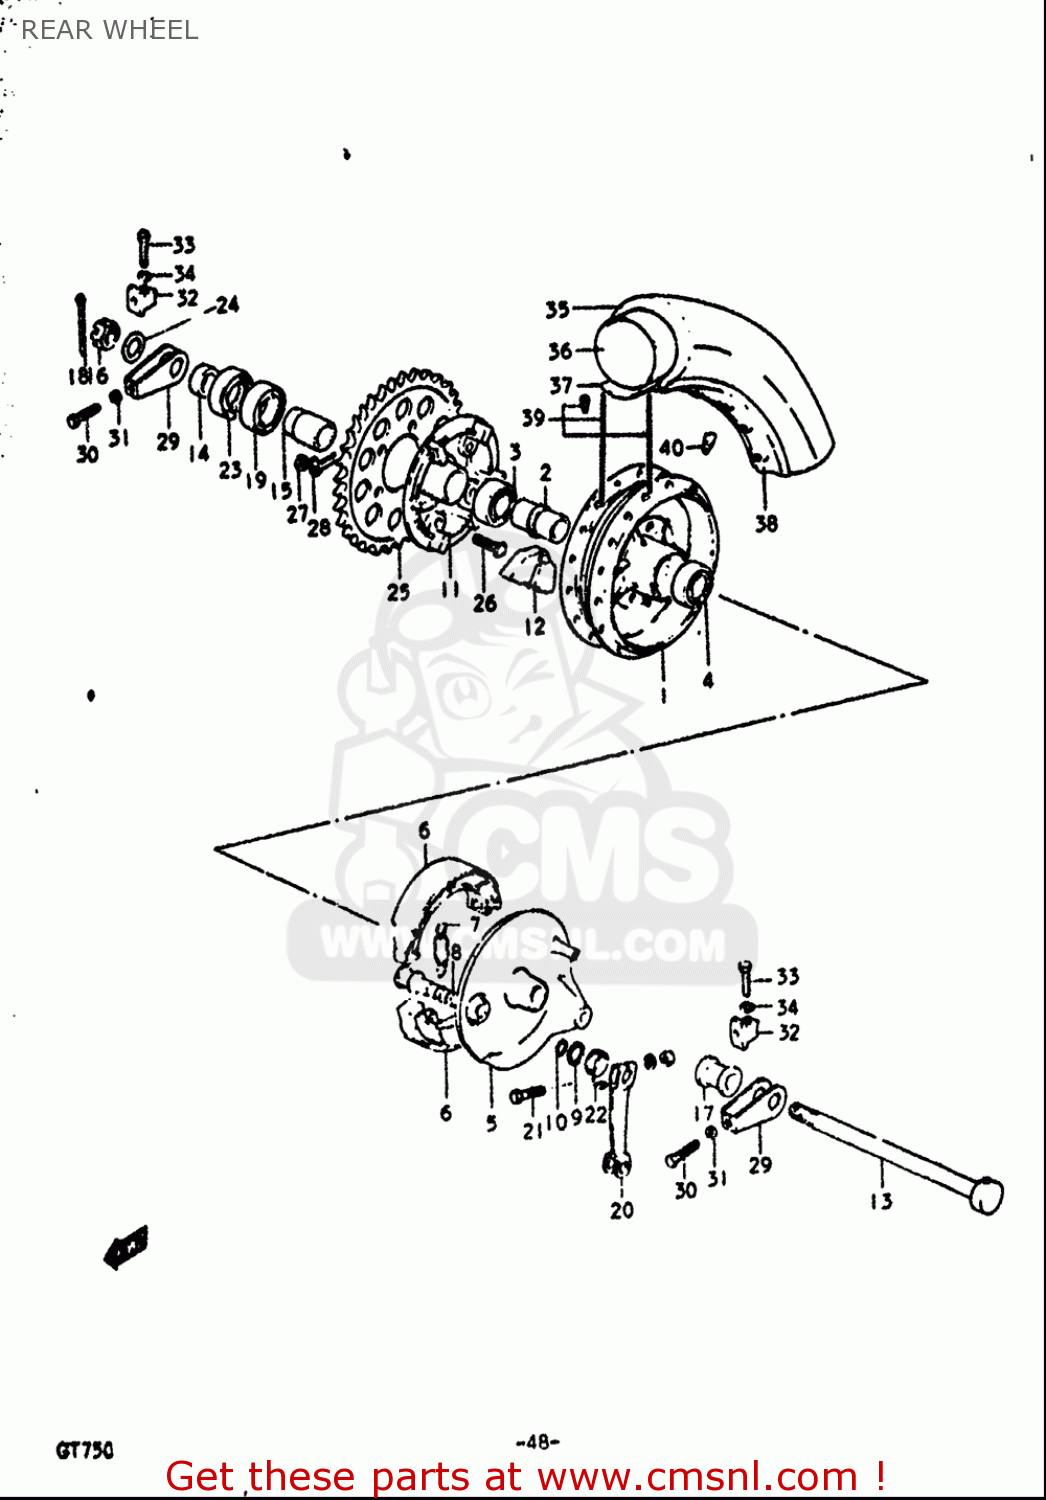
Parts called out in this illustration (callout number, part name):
3	BEARING
4	BEARING(20X47X14)
6	SHOE SET,BRAKE (NAS)
7	SPRING,BRAKE SHOE
8	CAM,RR BRAKE
9	WASHER(15.5X24X1.6)
10	O RING(D:2.4,ID:14.8)
11	DRUM,RR SPROCKET MOUNTING
12	ABSORBER,RR HUB SHOCK
15	SPACER,REAR HUB BEARING
16	NUT 18MM
18	PIN, COTTER
19	BEARING(25X62X17)
21	BOLT
22	SPRING
23	SEAL,OIL(33X62X7)
24	WASHER(19X34X4)
25	SPROCKET,REAR
26	BOLT(10X35.5)
27	NUT
28	WASHER
29	ADJUSTER,CHAIN
30	BOLT(8X50)
31	NUT
32	SUPPORTER,CHAIN ADJUST
33	BOLT
34	WASHER
36	TUBE,INNER
37	PROTECTOR,INNER TUBE
40	BALANCER,WHEEL (B)
